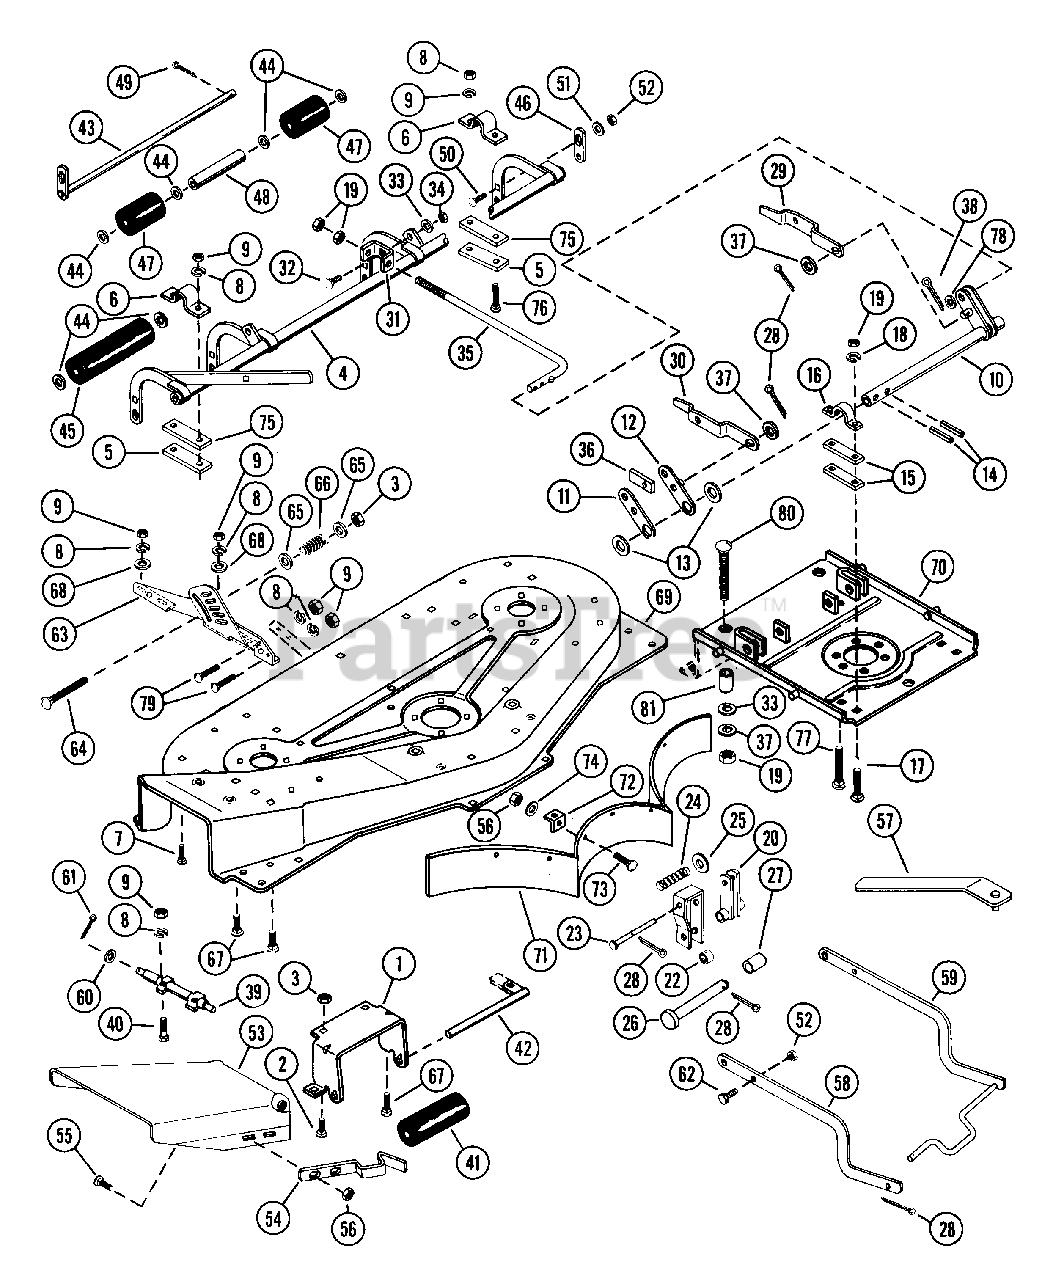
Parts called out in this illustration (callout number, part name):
1	BRACKET ROLLER
2	BLT-RDHDSQNK .312-18X.62 PL
3	NUT-LK .312-18 GR A PL
4	ROLLER FRAME
5	ADJUSTMENT PLATE
7	BLT-RDHDSQNK .31-18X1.0 SHT PL
8	WSHR-LK .312X.097 PL HVY
9	NUT-HEX .312-18
10	FRONT HANGER
11	OUTSIDE LINK
12	INSIDE LINK
13	WSHR-FL-STL .781X1.250X.059 PL
14	PIN-ROLL .250X1.25
17	BLT-RDHDSQNK .50-13X1.50 PL
18	WSHR-LK .500X.151 HVY PL
19	NUT .50-13 PL
21	SUPPORT CHANNEL
22	SPACER .516X.749X.938
23	PIN-CLEV .498X4.31 YWZC
24	SG-COMP .62X.68X1.75
25	WSHR-FL-STL .531X1.062X.095 PL
26	PIN-CLEV .498X4.50 YWZC
27	SPACER .390X1.000X.562
28	PIN-COTR .12X1.0 PL
29	LEVELING LEVER L.H.
30	LEVELING LEVER R.H.
32	BLT-RDHDSQNK .50-13X1.25 PL
33	WSHR-FL-STL .505X.880X.072 PL
34	NUT-LK-CTR .50-13
35	ADJUSTMENT ROD
36	WEAR PLATE
37	WSHR-FL-STL .511X1.441X.125 PL
38	PIN-COTR .12X.75 PL
39	HINGE PIN
40	BLT-SERRDHD SL .31-18X.75 YZ
42	ROLLER SHAFT
43	ROLLER SHAFT
44	WSHR-FL-STL.656X1.312X.095 PL
48	SPACER .726X.875X6.375
49	PIN-COTR .18X1.0 PL
50	BLT-RDHDSQSHNK .38-16X1.00 PL
51	WSHR-FL-STL .438X1.0X.083 PL
52	NUT-LK-CTR .375-16 GR A PL
53	CHUTE EXTENSION
54	SPRING, FLAT
55	BLT-RDHDSQNK .25-20X.50 SHT PL
56	NUT-LK-CTR .250-20 PL
58	HANGER ARM
59	MOWER HANGER
60	WSHR-FL-STL.406X.812X.065PL
61	PIN-COTR .09X.75 PL
62	BLT-HEX .38-16X1.00 PL GR5
63	HEIGHT QUADRANT
64	BLT-RDHDSQNK .31-18X1.75 PL
65	WSHR-FL-STL .38X.875X.083 PL
66	SG-COMP .063X.53X1.187
67	BLT-RDHDSQNK .31-18X.75 GR5 PL
68	WSHR-FL-STL .323X.625X.062 PL
69	48 INCH MOWER PAN W/DECALS
70	MOUNTING PLATE
77	BLT-RDHDSQNK .50-13X1.75 PL
78	WSHR-FL-STL .469X.937X.065 PL
80	BLT-RDHDSQNK .50-13X2.75 SHTPL
81	SPACER .512X.747X1.567
